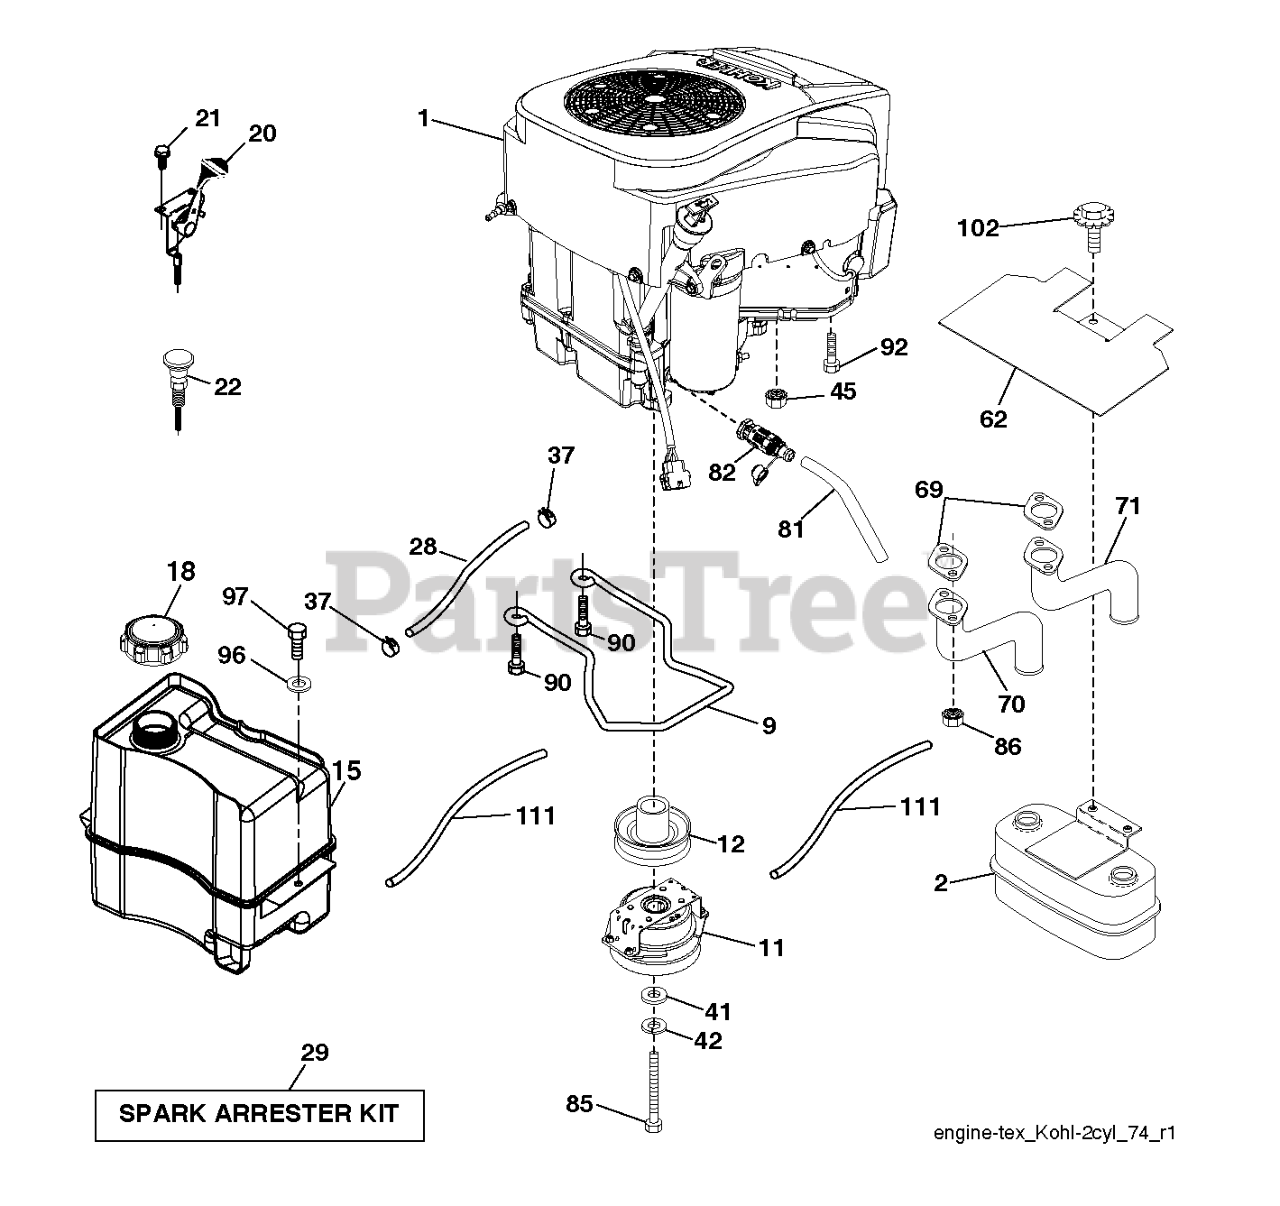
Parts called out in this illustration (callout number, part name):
2	MUFFLER.ASM.TWIN.MNTG.BRACKET
9	KEEPER.BELT.ENG.4.25"2.BLT.431
11	CLUTCH.OGURA.5.0PD.GT1.5A-EH07
12	PULLEY.ENGINE.TUFFTORQ
15	Tanks
18	CAP.2.25'.VENTED.TETHER .EPA
20	THROTTLE CONTROL
21	SCREW.#10 X 0.750.BOS
22	CONTROL.CHOKE.ERGO.PUSH-IN.BLA
28	LINE.FUEL.20"FRONT.EMI
29	KIT.SPARK ARRESTOR 794945 B&S
37	HOSE CLAMP
42	WASHER 7/16 LOCK
45	NUT
62	SHIELD.HEAT.MUFFLER
69	GASKET.EXHAUST.KOHL.CV18-CV26
70	PIPE.EXHAUST.LH.CV18/20
71	PIPE.EXHAUST.RH.CV18/20
81	TUBE, DRAIN OIL ASM.
82	VALUE.OIL.DRAIN
85	BOLT.HEX.7/16-20X3.75.GR5.RED
86	NUT.HEX.FLANGE.TOPLOCK
90	SCREW 3/8-16X1
92	SCREW 3/8-16X1
97	SCREW HEXWSHR 1/4-20X3/4
102	SCREW
111	RP PURGE LINE
